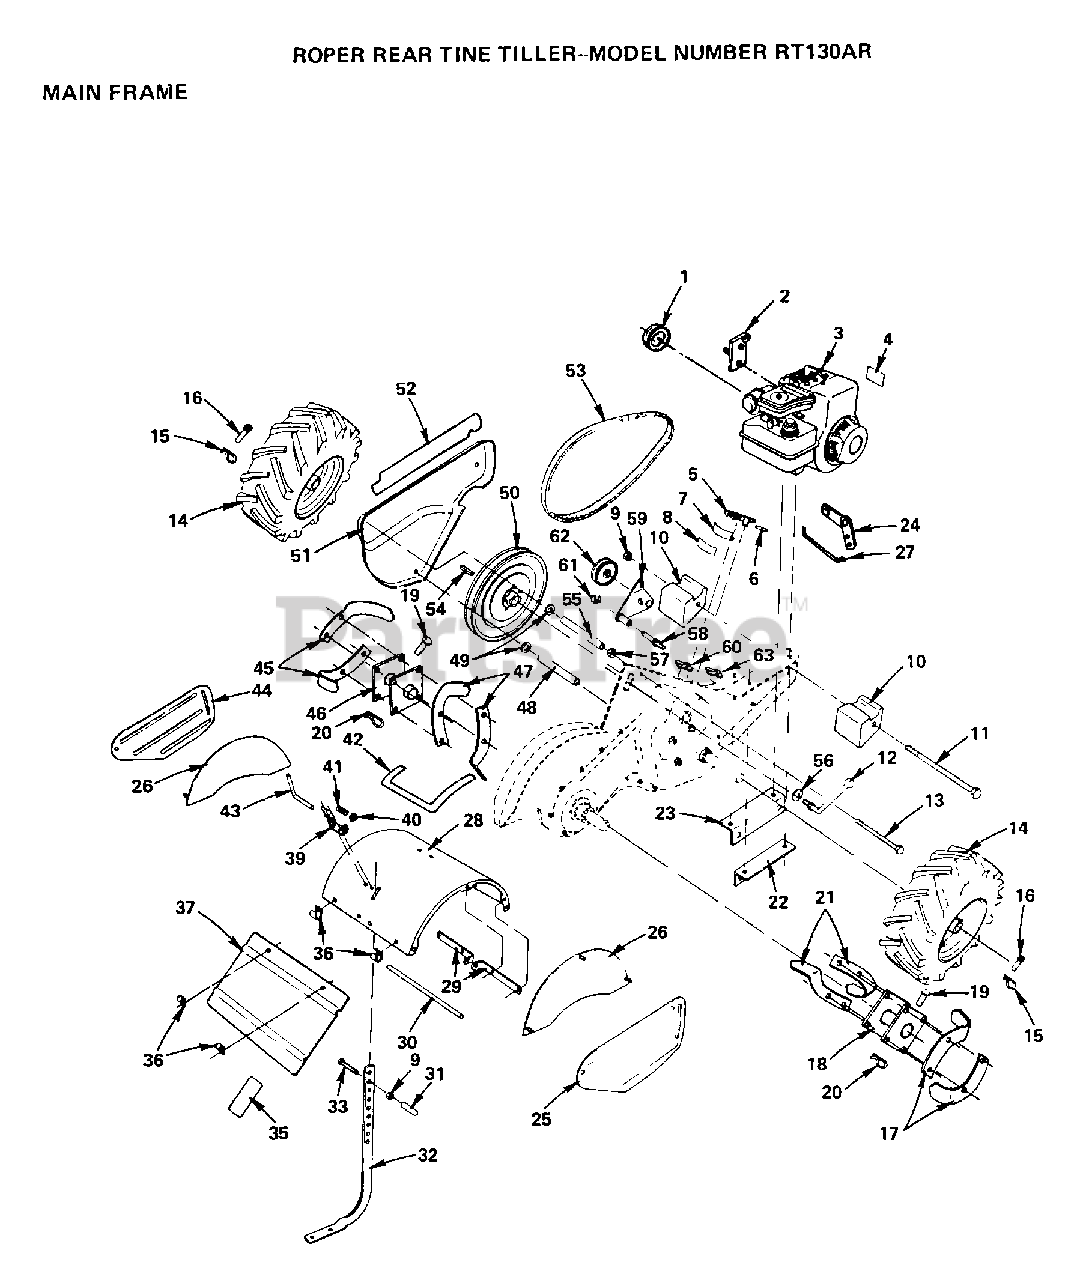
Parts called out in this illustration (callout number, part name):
2	BRACKET ASSY CRT
3	ENGINE, B&S
8	DECAL CRT
9	NUT.HEX.3/8-16UNC
10	COUNTERWEIGHT CRT
11	BOLT CRT
13	BOLT-HEX TI
15	RETAINER M
19	RIVET.PAN HD.1.75
22	BRACKET RH CRT
23	BRACKET LH CRT
31	GRIP CRT
33	BOLT
36	HINGE CRT
39	LATCH BRACKET TI
40	KLIP RING TI
41	SPRING TI
43	STAKE PIN TI
49	WASHER
50	"SHEAVE 10"" CRT"
52	DECAL - BELT GUARD
54	KEY T
56	WASHER
57	NUT.HEX.5/16-18
58	SHIFT ARM CRT
60	CONDIUT CLIP T
61	KLIP RING
62	PULLEY-IDLER TI
63	CLAMP
